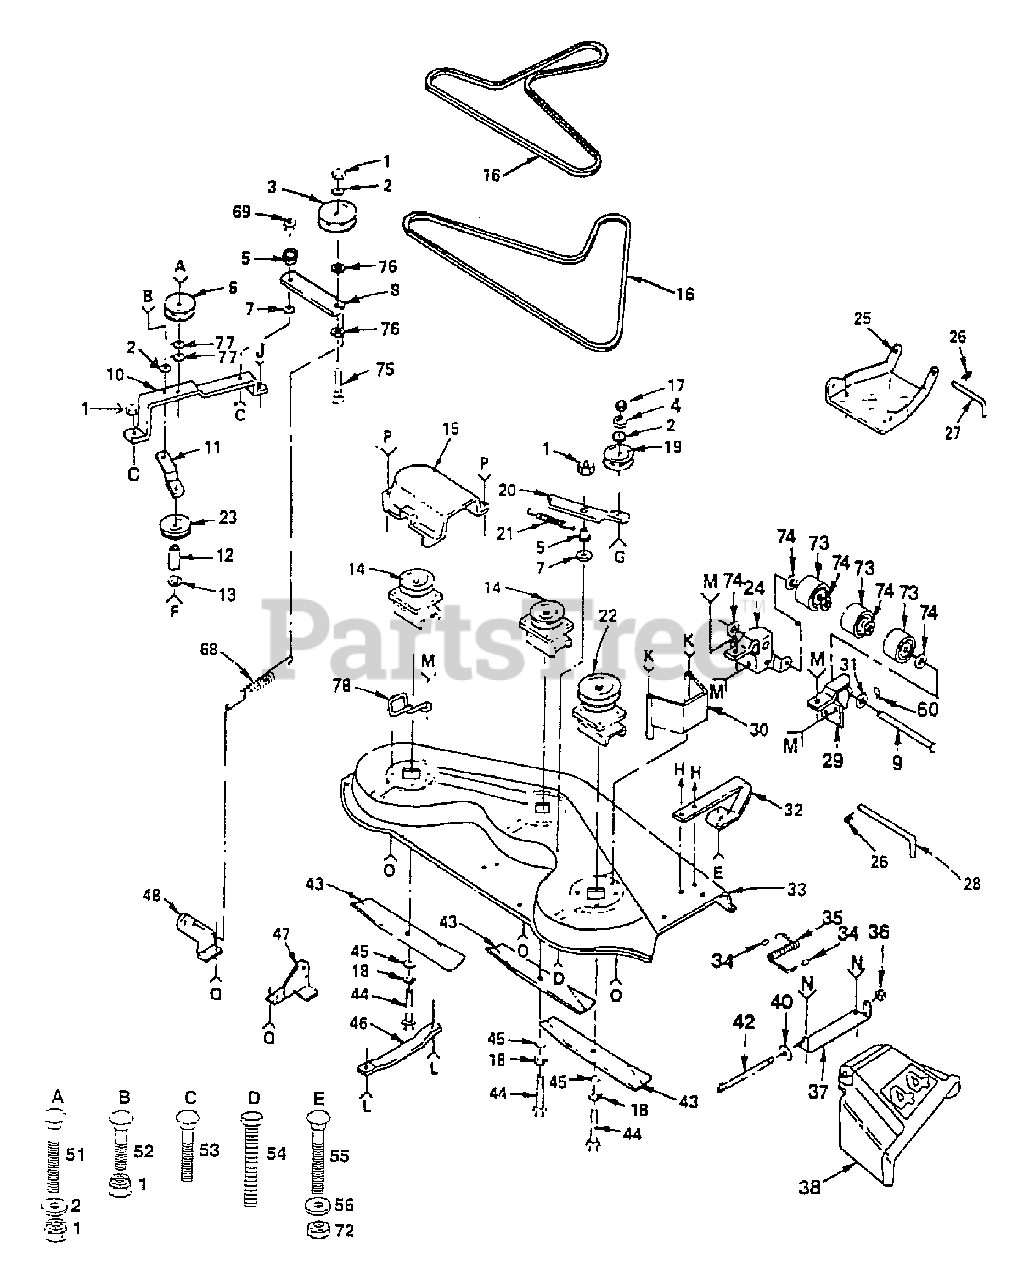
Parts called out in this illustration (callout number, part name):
1	Nut, Crownlock 3/8-16
2	Washer 13/32 x 1 x 14 Gauge
3	Pulley, Idler
4	Washer, Lock 3/8
6	Pulley, Idler
7	Washer, Wear
8	Arm, Idler
9	Pin, Pivot
10	Bar, Support, Idler
11	Brace, Idler, Deck
13	Washer 13/32 x 13/16 x 16 Gauge
14	Mandrel, Secondary
17	Nut, Hex 3/8-16
18	Washer, Lock 3/8
19	Idler, Flat
20	Arm, Idler, Deck
21	Spring, Extension
22	Mandrel, Primary
23	Pulley, Idler
24	Bracket, Lift, L.H.
25	Link, Parallel
26	Retainer, Spring
27	Pin, Front, Hinge
28	Pin, Rear, Hinge
29	Bracket, Lift, R.H.
30	Guard, Belt, R.H.
31	Washer 15/32 x 1 x 16 Gauge
32	Runner, R.H.
33	Housing, Mower
34	Cap, Sleeve
35	Spring
37	Bracket, Deflector
38	Guard, Discharge
40	Washer 11/32 x 5/8 x 16 Gauge
42	Rod, Hinge
43	Blade, Mower
44	Bolt, Hex 3/8-24 x 1-1/2 Grade 5
45	Washer 13/32 x 1-1/4 x 12 Gauge
46	Runner, L.H.
47	Bracket, Suspension, Rear, R.H.
48	Bracket, Suspension, Rear, L.H.
51	Bolt, Carriage 3/8-16 x 1-3/4
52	Bolt, Carriage 3/8-16 x 1
53	Bolt, Carriage 3/8-16 x 1-1/2
54	Bolt, Hex 3/8-16 x 1-1/2
55	Bolt, Carriage 5/16-18 x 3/4
56	Washer 11/32 x 11/16 x 16 Gauge
60	Pin, Cotter 1/8 x 3/4
68	Spring, Extension
69	Nut, Centerlock 3/8-16
72	Locknut 5/16-18
73	Roller, Nose
74	Washer 15/32 x 1 x 10 Gauge
75	Bolt, Carriage 3/8-16 x 2-1/2
76	Washer 13/32 x 3/4 x 10 Gauge
77	Washer 13/32 x 7/8 x 10 Gauge
78	Keeper, L.H., Mandrel, Belt
